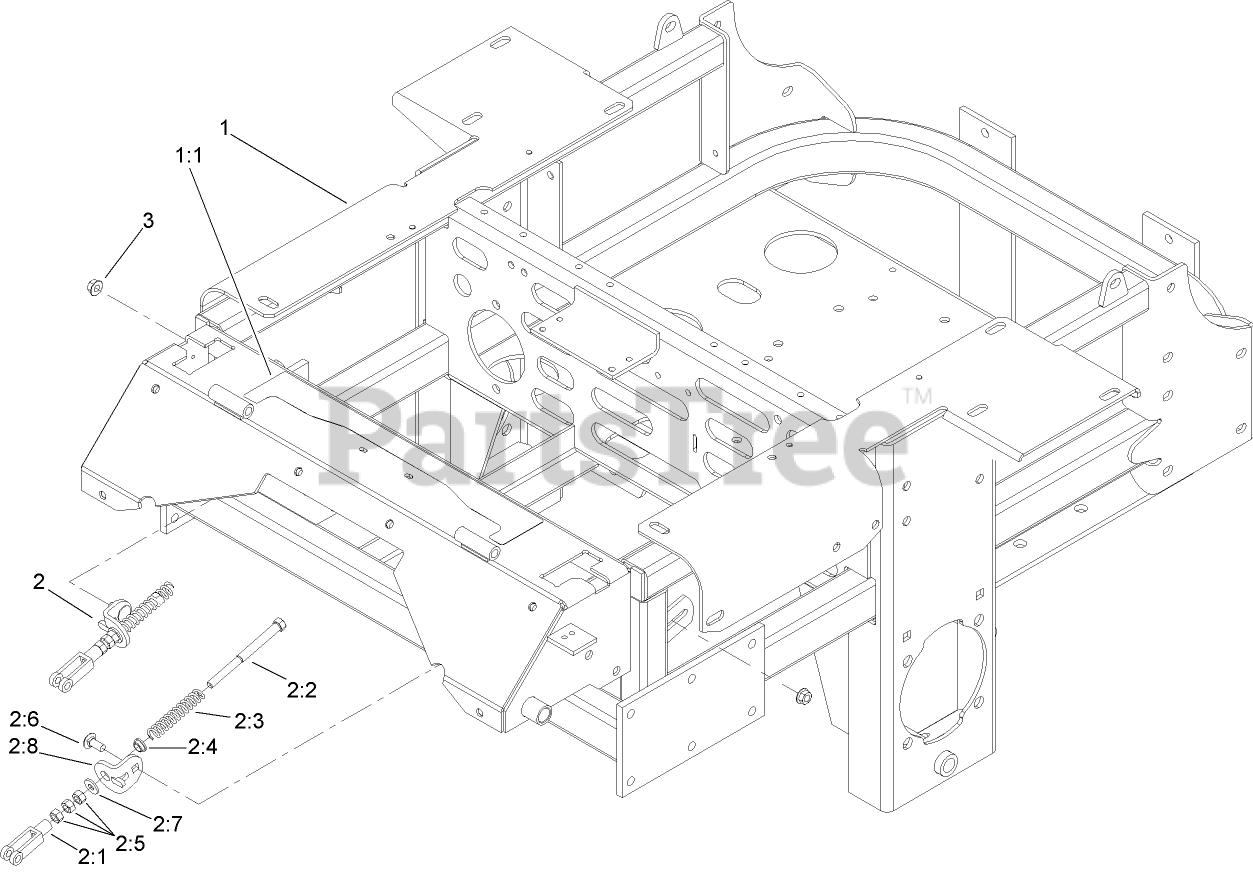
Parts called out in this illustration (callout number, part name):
1	MAIN FRAME ASM (W/DECALS-CE)
1:1	DECAL-CONSOLE, TOP
2	NEUTRAL RETURN ASM
2:1	YOKE-ADJUSTABLE
2:2	BOLT-RETURN, NEUTRAL
2:3	SPRING-RETURN, NEUTRAL
2:4	BUSHING-NYLON, FLANGED
2:5	NUT-HEX
2:6	SCREW-CARR
2:7	WASHER-FLAT
2:8	TAB-ADJUSTMENT
3	NUT-HF
